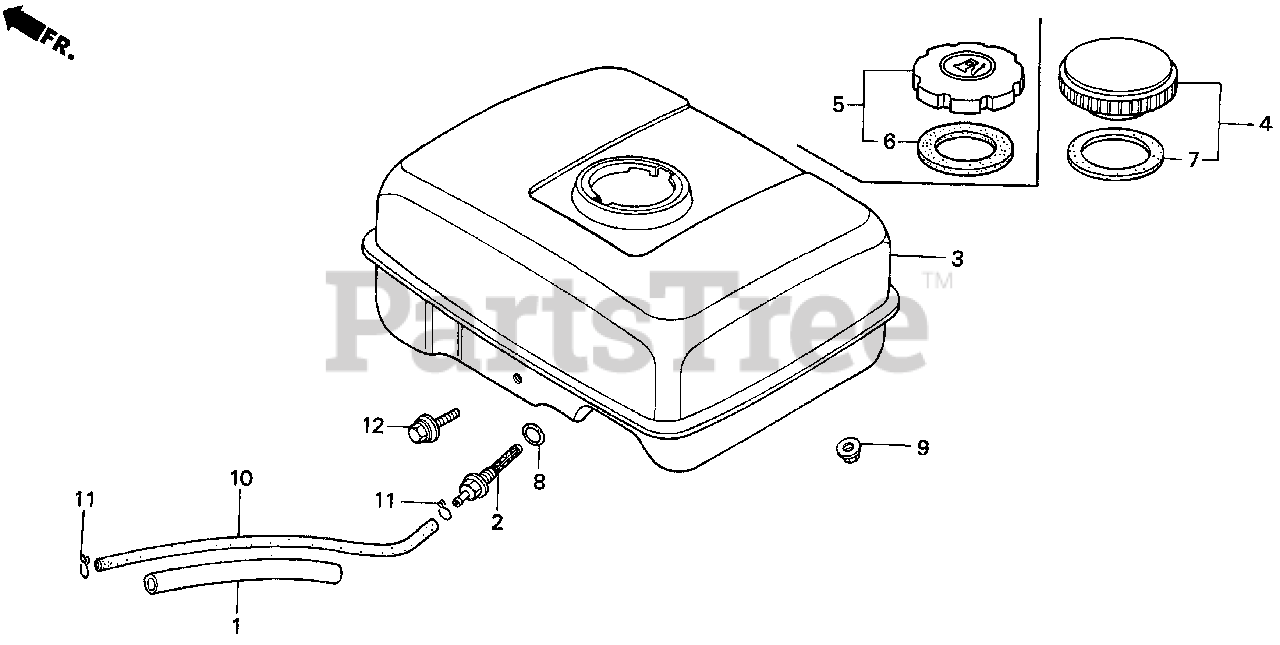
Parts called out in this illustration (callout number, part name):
1	RUBBER, SUPPORTER (107MM)
2	JOINT, FUEL TANK
3	TANK, FUEL *R280* (POWER RED)
4	CAP, FUEL FILLER
5	CAP, FUEL FILLER (BLACK)
6	GASKET, FUEL FILLER CAP (39X58X3)
7	GASKET, FUEL FILLER CAP (39X58X3)
8	O-RING (13.5X1.5) (ARAI)
8	O-RING (14MM) (NOK)
9	NUT, FLANGE (6MM)
10	BULK HOSE, FUEL (4.5X3000) (4.5X140)
11	CLIP, TUBE (B8)
12	BOLT, FLANGE (6X25)
